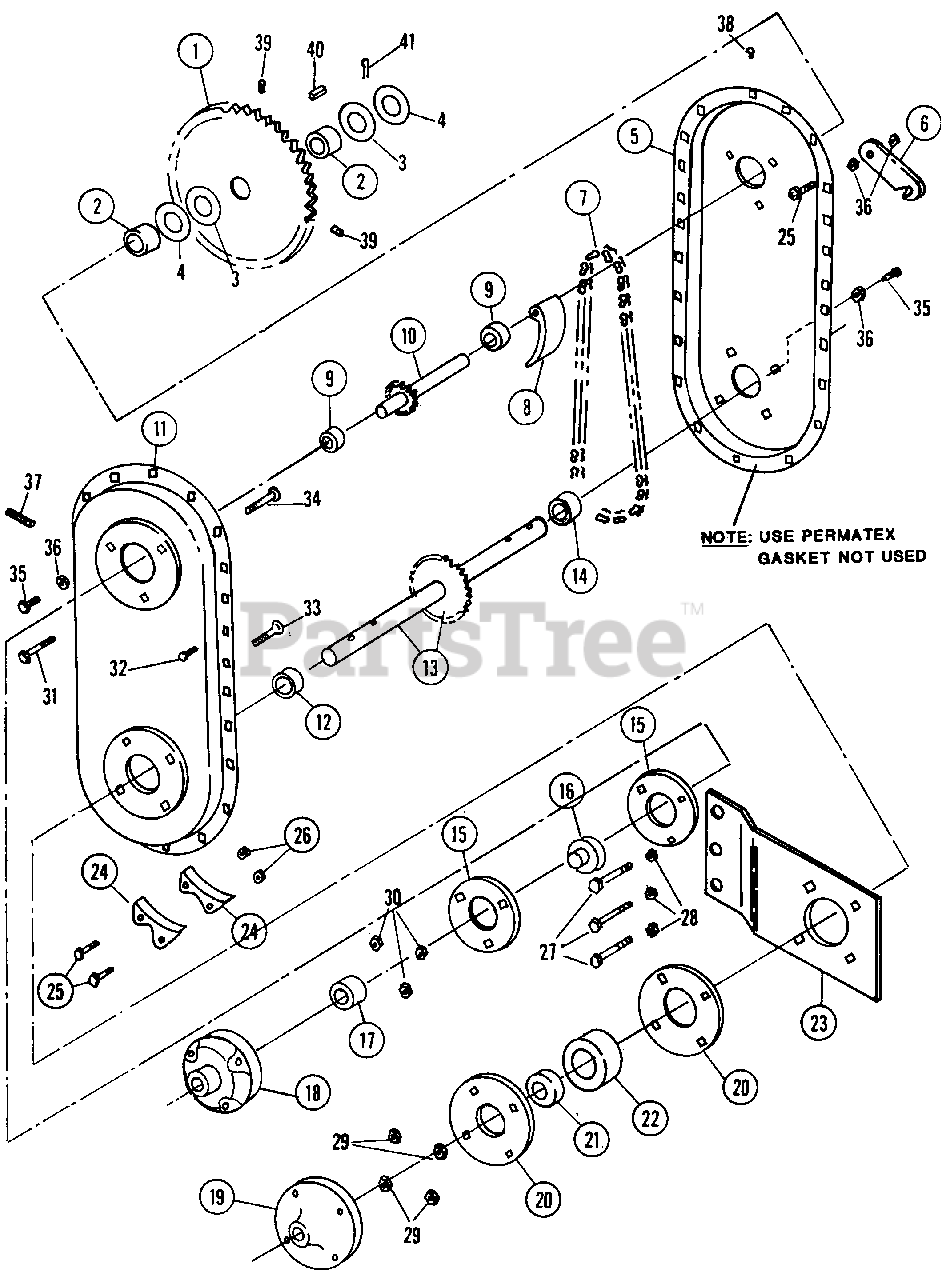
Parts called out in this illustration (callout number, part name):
1	SPROCKET, 40 TOOTH
2	SPACER, 40T SPROCKET
3	WASHER, SPECIAL (INNER)
4	WASHER, SPECIAL OUTER
5	HOUSING, RIGHT SIDE CHAIN
6	STRAP, HINGE LOCK
7	CHAIN, ROLLER DRIVE ASA 60, 50 Pitches
8	PADDLE, CHAIN TIGHTENER
9	SPACER, UPPER SHAFT 1.05" DI x 1.312" OD x .41"
10	SPROCKET SHAFT
11	HOUSING, LEFT SIDE CHAIN
12	SPACER, TINE SHAFT SHORT
13	TINE SHAFT & SPROCKET
14	SPACER, TINE SHAFT LONG
15	FLANGETTE, 3-HOLE
16	BEARING, SPROCKET SHAFT
17	LOCK-COLLAR, BEARING
18	HUB, PIVOT
19	CAP, BEARING GUARD (DUST)
20	FLANGETTE, 4-HOLE
21	LOCK-COLLAR, TINE SHAFT BEARING
22	BEARING, TINE SHAFT
23	PLATE, LOWER ATTACHING
24	WEAR-BAR
25	BOLT, 1/4-20 x 2"
26	LOCKNUT, 1/4-20 HEX
27	BOLT, 1/2-13 x 2 HEX HEAD
28	LOCKNUT, 1/2-13 HEX
29	LOCKNUT, 3/8-16 HEX
30	LOCKNUT, 5/16-18 HEX
31	BOLT, 5/16-18 x 2 HEX HEAD
32	BOLT, Carriage 1/4C X3/4 GR5 YZ
33	BOLT, 3/8-16 x 1-3/4 CARRIAGE
34	BOLT, 5/16-18 x 1-1/2 CARRIAGE
35	BOLT, 1/4-20 x 1/2 SN CARRIAGE
36	LOCKNUT, 1/4-20 HEX
37	SETSCREW, HEX SOCKET HEAD 5/16-18x1.5 (Use 7091590)
38	COVER, OIL HOLE
39	SETSCREW, 5/16 x 1/4
40	KEY, 1/4 SQUARE x 1
41	COTTER-PIN, 1/8D x 1-1/4
